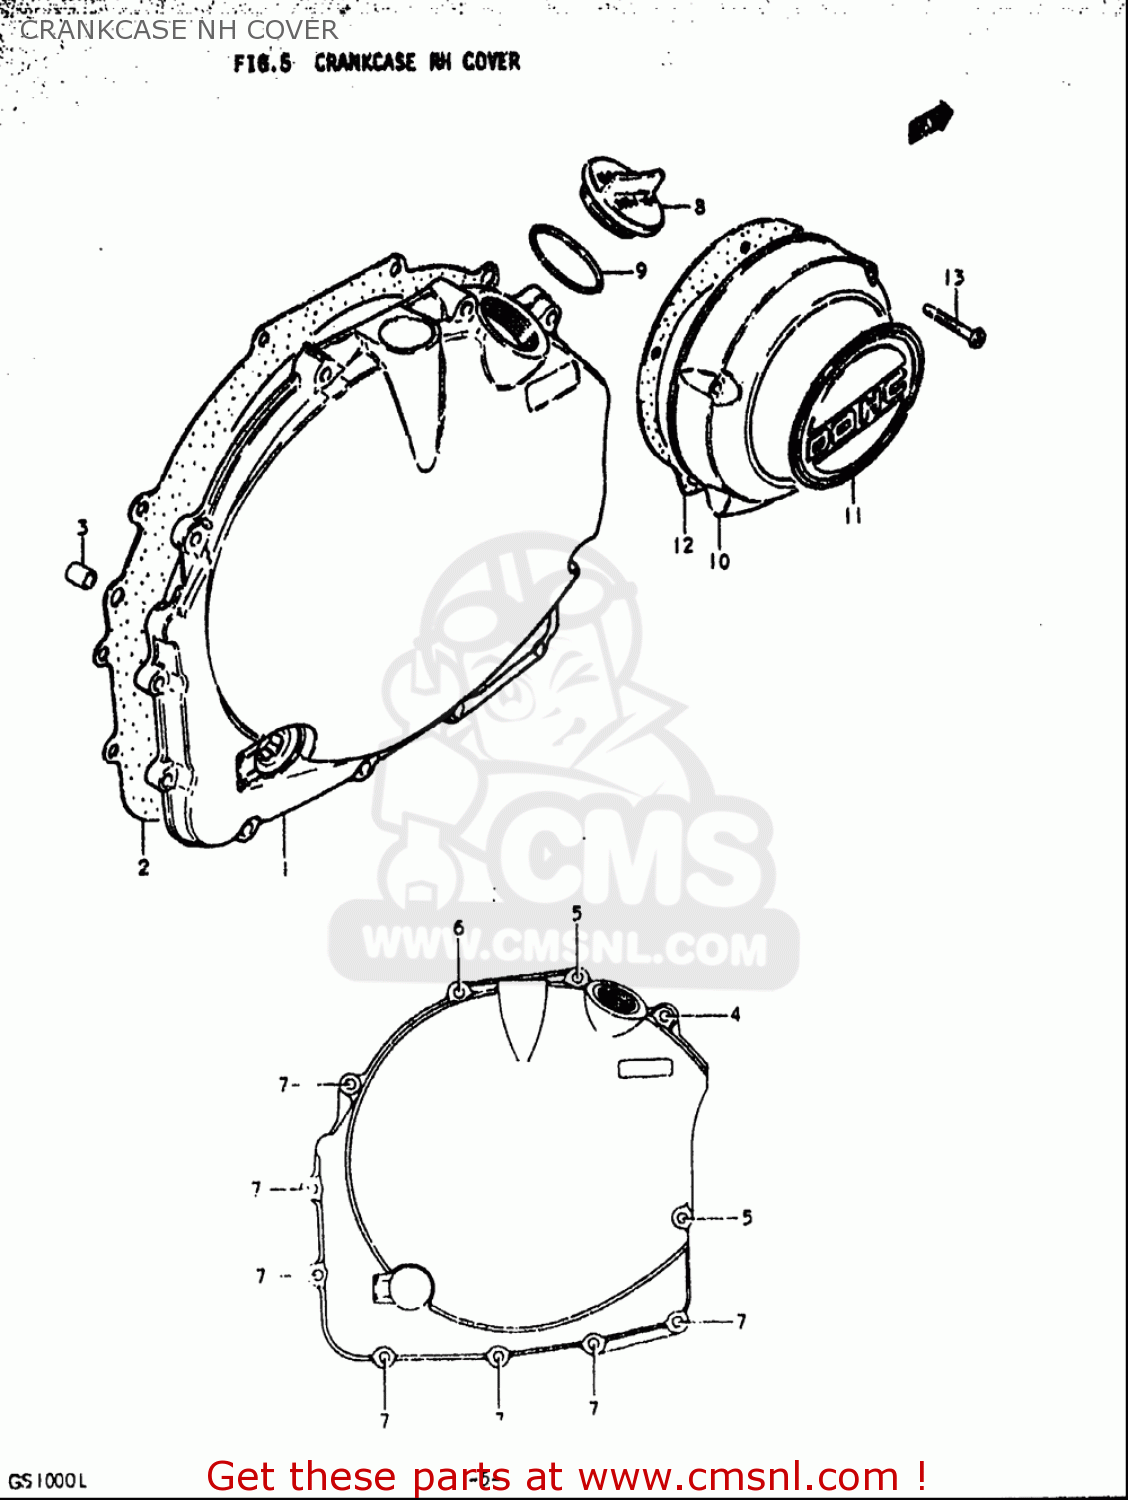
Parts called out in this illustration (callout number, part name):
2	GASKET,CLUTCH COVER (NAS)
3	PIN
4	SCREW
5	SCREW
6	SCREW
7	SCREW
8	PLUG SET
9	O RING(D:2.2,ID:32)
10	COVER,CONTACT BREAKER
11	EMBLEM,CONTACT BREAKER COVER
12	GASKET,CONTACT BREAKER COVER (NAS)
13	SCREW
